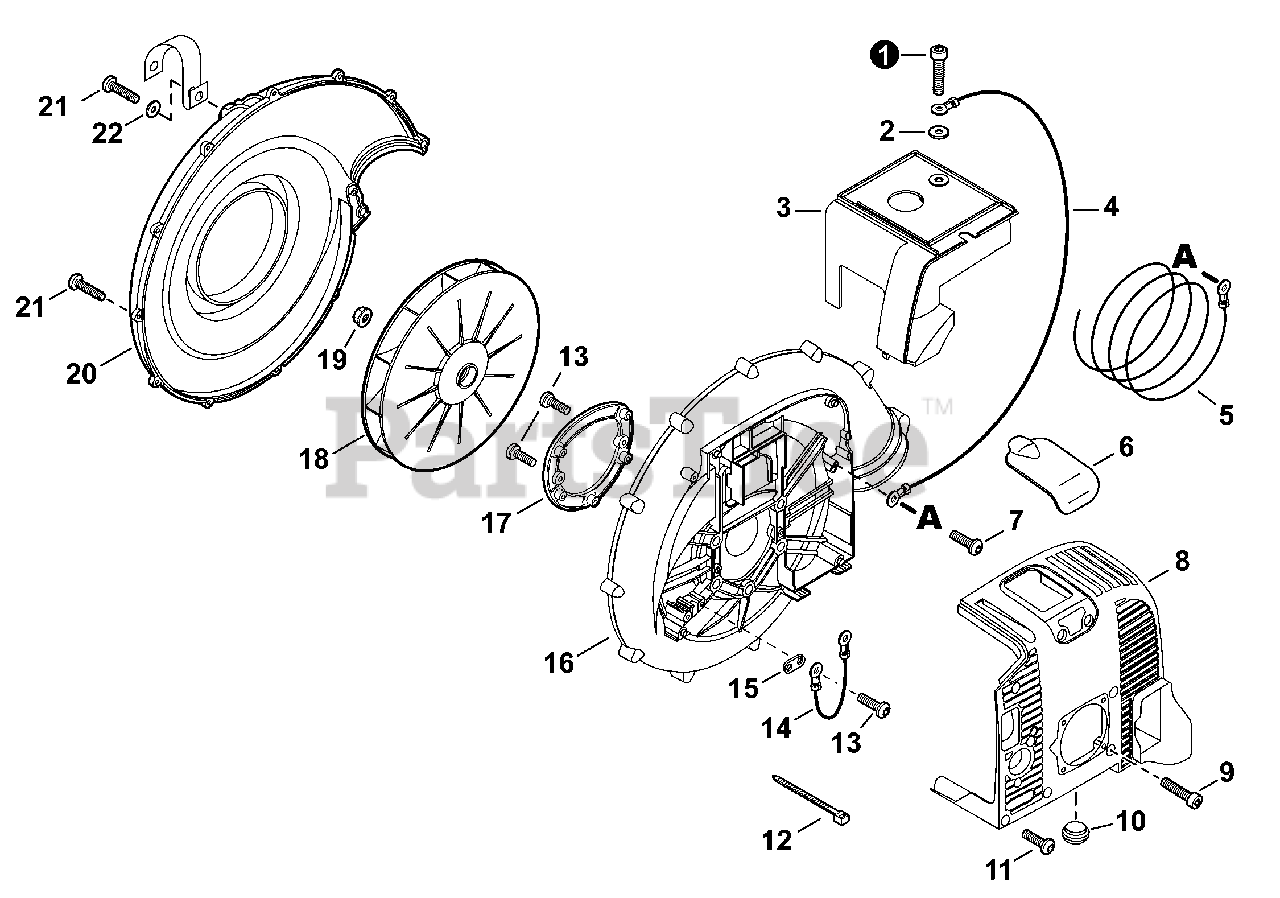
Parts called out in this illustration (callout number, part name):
1	SCREW 5×20
2	WASHER 5.2×14×T3
3	COVER, CYLINDER
4	LEAD L= 195 mm
5	WIRE, STATIC DISCHARGE 890mm
6	COVER, SPARK PLUG
7	BOLT, TORX 5×12
8	COVER, ENGINE
9	SCREW 5×16
10	CUSHION
11	BOLT, TORX 5×20
12	STRAP, TIE
13	BOLT, TORX 5×16
14	LEAD L= 295 mm
15	PLATE, EYE
16	CASE, FAN
17	PLATE, ENGINE
18	FAN, BLOWER
19	NUT, FLANGE 10×1.25
20	COVER, FAN
21	BOLT, TORX 5×20
22	WASHER 5.5×16×2T
